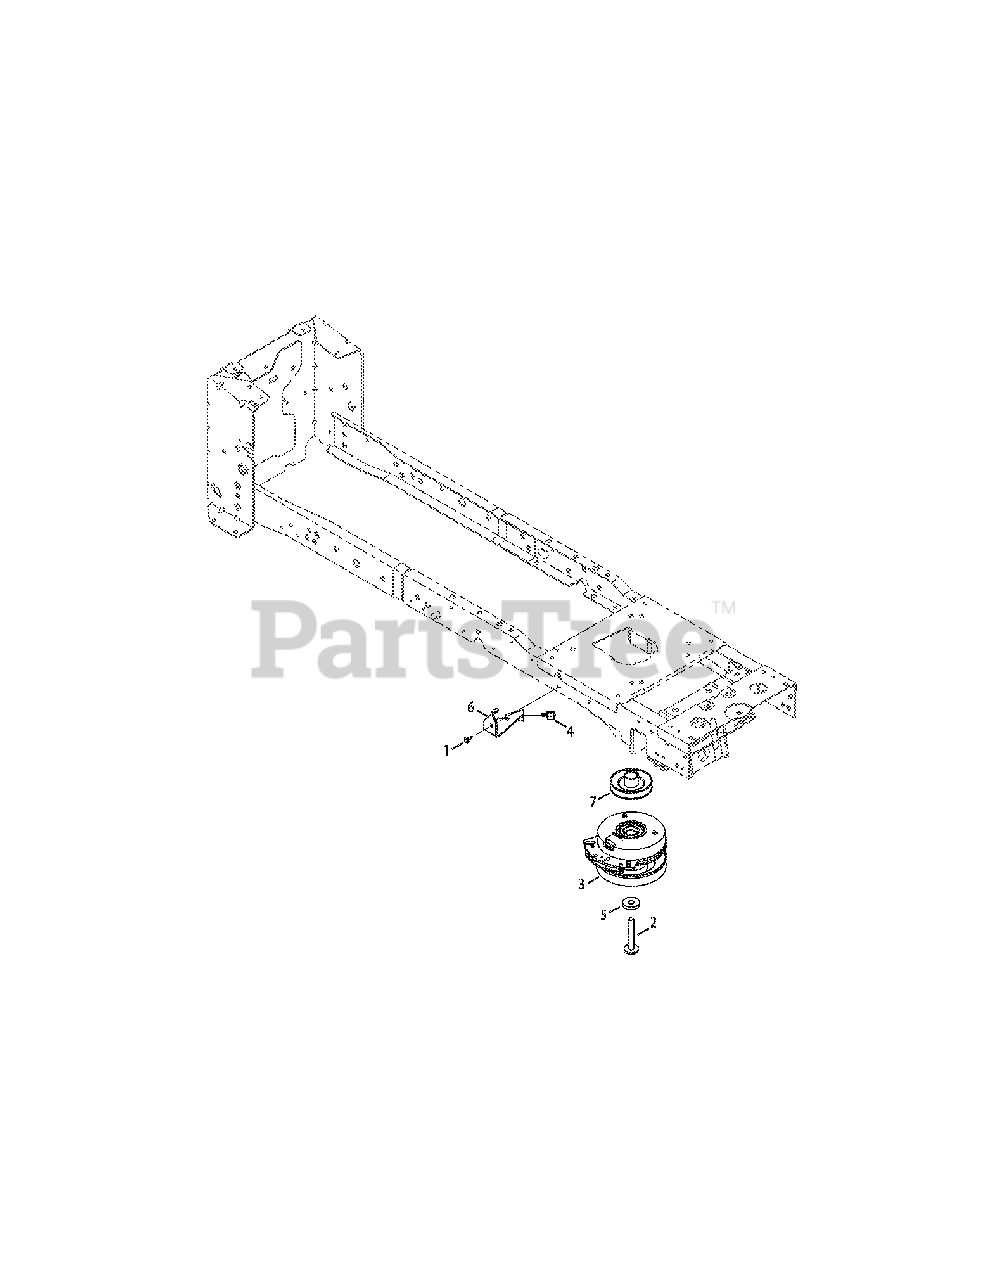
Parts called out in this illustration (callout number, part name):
1	Screw, M6-1 x .625
2	Hex Cap Screw, 7/16-20 x 3.50
3	Clutch, Electric PTO
4	Grommit
5	Flat Washer, .450 x 1.375 x .250
6	Clutch Bracket
7	Engine Pulley
